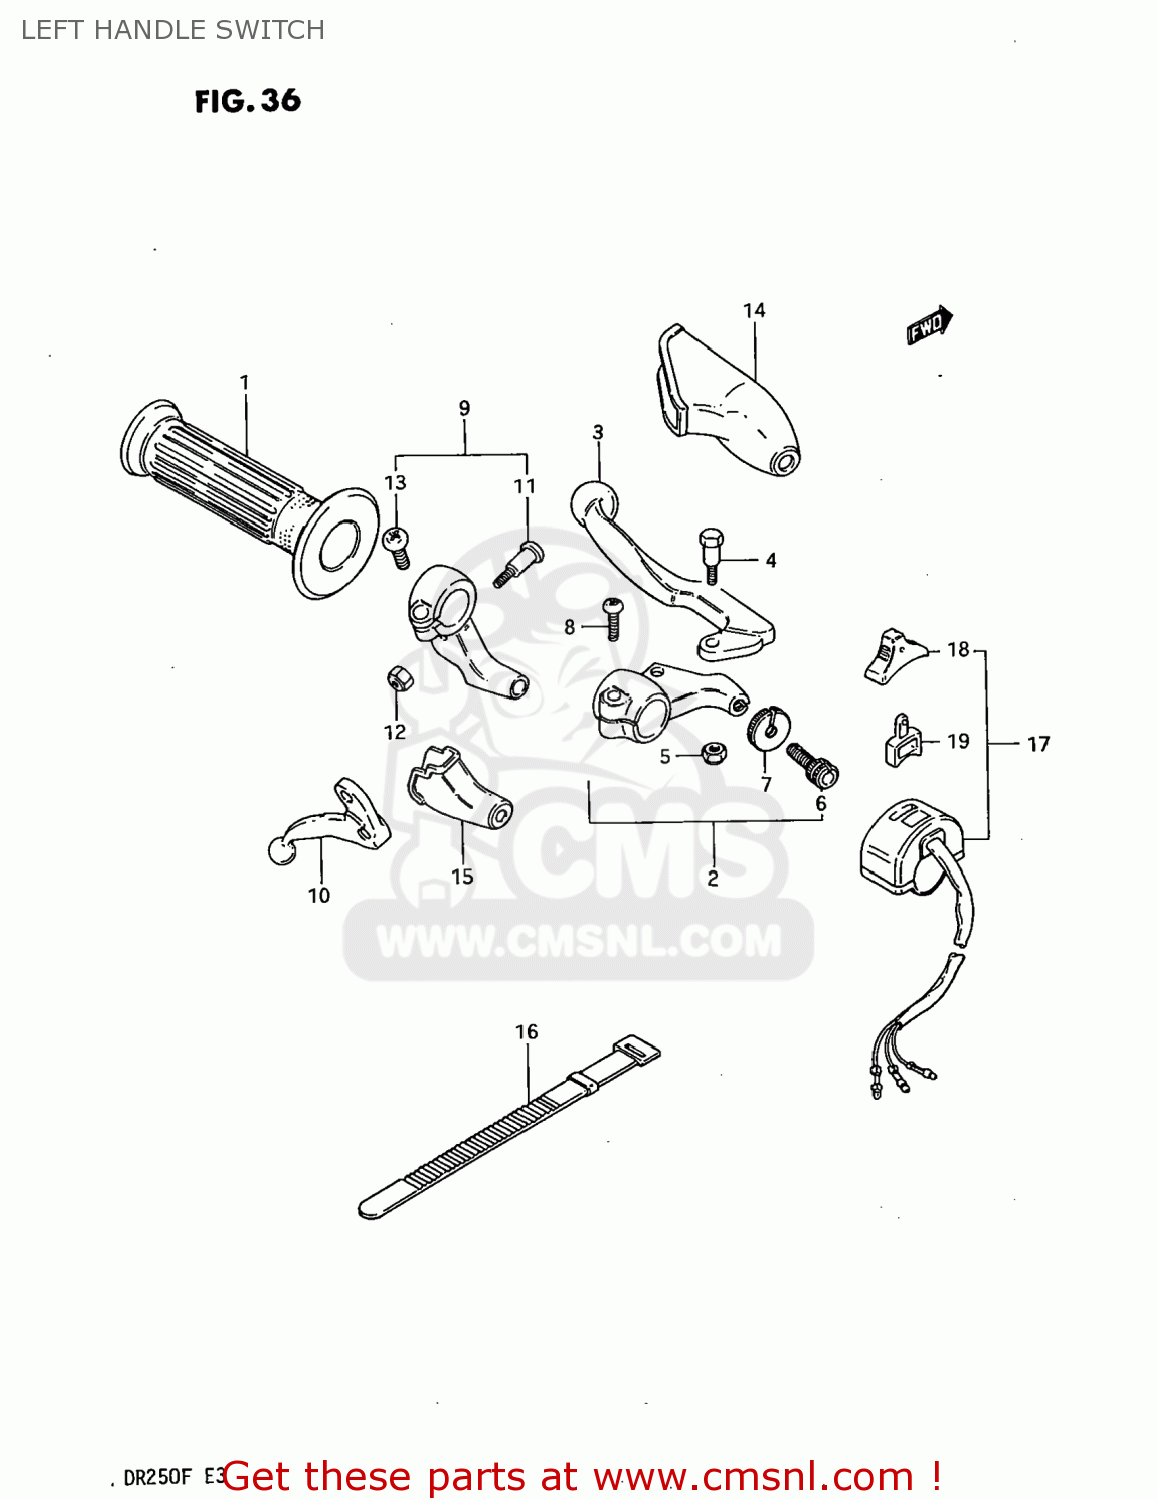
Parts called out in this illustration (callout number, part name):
1	GRIP,L
2	LEVER ASSY,CLUTCH
3	LEVER,CLUTCH
4	BOLT,LEVER
5	NUT 6MM
6	ADJUSTER,CABLE
7	NUT,CABLE ADJUSTER
8	SCREW
9	LEVER ASSEMBLY,DECOMPRESSION
10	LEVER,DECOMP
11	BOLT,LEVER
12	NUT
13	SCREW
14	COVER,CLUTCH LEVER
15	COVER,DECOMP LEVER DUST
16	CLAMP(L:120)
17	SWITCH ASSY,LIGHTING
18	KNOB,LIGHTING & DIMMER
19	BLOCK,LIGHTING/DIMMER
